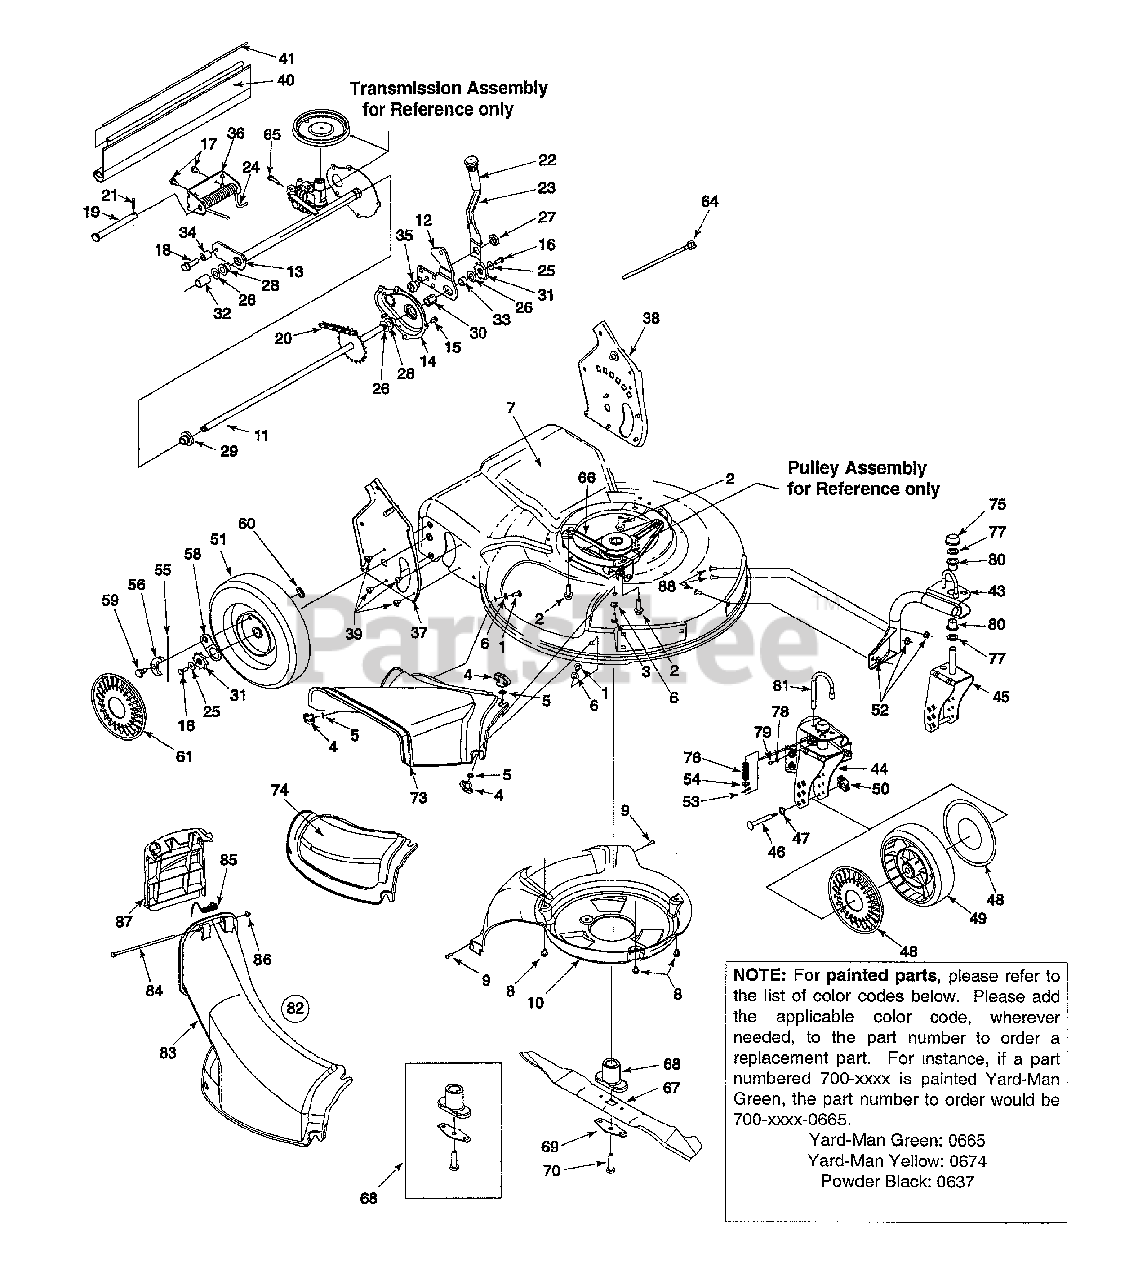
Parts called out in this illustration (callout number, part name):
1	Scr. Carr. 1/4-20 x .62
2	Scr. TT:3/8-18:1.00
3	Carriage Scr. 1/4-20 x .750
4	Wing Nut 1/4-20
5	Nut, Push .25 I.D. x .50 O.D.
6	Wash. Fl. .334 I.D.x .62 x.03
8	Scr. TT. 1/4-20 x .375
9	Scr. HL. 1/2-14 x .750
11	Rear Axle Assembly
12	Pivot Arm Assembly
13	Trans. Axle Assembly
14	Chain Cover Assembly
15	Scr. TT 1 /4-20 x .375
16	Cap Screw HH 1/4-20 x .620
17	Scr. AB 1/4-20x.625
18	Scr. 3/8 116 x .25
19	Clevis Pin .50 Dia. x 4.82 Lg.
20	Chain-Endls. #48 .500P x 24L
21	Cotter Pin .125 O.D. x .75
23	Spring Lever
24	Torsion Spring
25	Bell Wash. .285 x .75 x .082
26	Fl. Wash .508 I.D. 1.000 x .
27	Nut Shld. .825 Dia. x .165 Lg.
28	Hx.Flg. Brg .506 I.D. x .590 L.
29	Hx.Flg. Brg .506 I.D. x.715 L.
30	Hx. Slv. Brg .504 I.D. x .830 L.
31	Wheel Rachet
32	Spa. .550 I.D. x /750 O.D.
33	Spa. .51 .D. x .70 O.D. x 38 L.
34	Spa. .385 x .624 x .700
35	Shld. Spa. .385 I.D. X .715 Lg.
36	Brkt. - Ht. Adj. Spring
40	Trail Shield
41	Trail Shield Wire
46	Caster Axle .374 Dia x 2.50"
47	Wave Washer
48	Hub Cap, Yellow w/ hole
49	Wheel 7 x 2 Link
50	Wing Nut 1/4-20
51	Wheel 9 x 2 Link
52	Lock Nut 5/15-18
53	Cotter Pin .072 x .12 Lg.
54	Fl. Wash. .330 x .830 x .060
55	Spring, Ratchet, Plastic
56	Pawl - R.H.
56	Pawl - L.H.
58	Ratchet Pawl Plate
59	Scr. Shld. .340 x .285
60	Top Lock Tab Weld Nut 1/4-20
61	Hub Cap: Radial Spoke Yell
63	Engine Shroud
64	Cable Tie
65	Hex Scr. 5/16-18
66	Belt, 3/8" x 39.24"
67	21" Mulching Blade
68	Blade Adapter
69	Blade Bell Suport
70	Hex Bolt 3/8-24 x 2.5"Lg.
73	Side Discharge Chute
74	Mulch Cover
75	Push Cap
76	Compression Spring
77	Fl. Wash. .5/8 I.D. x 1" O.D.
78	Fl. Wash. .203 x .403 x .040
79	Fitting - Grease
80	Flange Bearing
81	Locking Pin
82	Chute Assembly
83	Discharge Chute
84	Pivot Rod
85	Torsion Spring
86	Push Cap
87	Chute Door
88	Carr. Bolt 5/16-18 x.62
